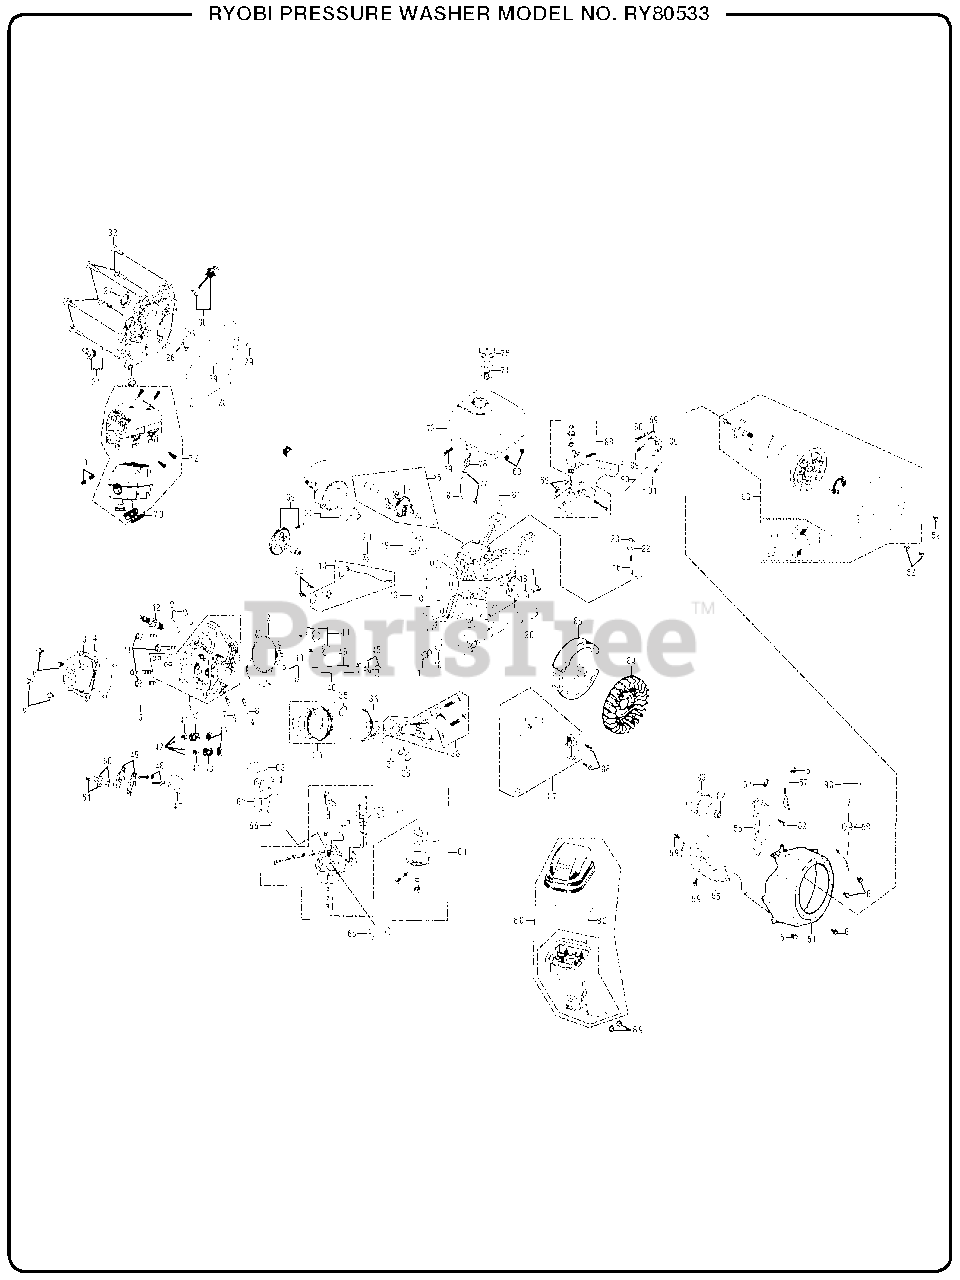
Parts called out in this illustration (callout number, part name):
1	Cylinder Head Sub-assembly
2	Cylinder Head Gasket
3	Cylinder Head Cover Sub-assembly
4	Cylinder Head Cover Gasket
11	Cylinder Head Bolt
13	Crankcase Sub-assembly
14	Engine Oil Sensor
15	Governor Gear Assembly
22	Governor Gear Washer
25	Crankcase Cover
28	Crankcase Gasket
30	Oil Dipstick Sub-assembly
31	Engine Oil Plug Sub-assembly
33	Crankshaft Assembly
34	Piston Ring Assembly
35	Piston Pin Clip
36	Piston Assembly
39	Camshaft Assembly
41	Valve Spring Seat
42	Valve Lock Clip
47	Lifter Stopper Plate Sub-assembly
48	Valve Adjusting Bolt
50	Valve Adjusting Nut
53	Recoil Starter Assembly
55	Cylinder Body Shroud
58	Stop Engine Switch Assembly
60	Governor Support Bolt,
63	Insulator Carburetor Gasket
64	Carburetor Assembly
65	Air Cleaner Gasket
66	Carburetor Gasket
67	Carburetor Insulator Plate
72	Muffler Assembly
75	Fuel Tank Cover
76	Fuel Tank Oil Outlet Assembly
80	Governor Support Sub-assembly
85	Flywheel Sub-assembly
87	Ignition Coil
88	Throttle Control Assembly
89	Governor Spring
91	Throttle Valve Returning Spring
